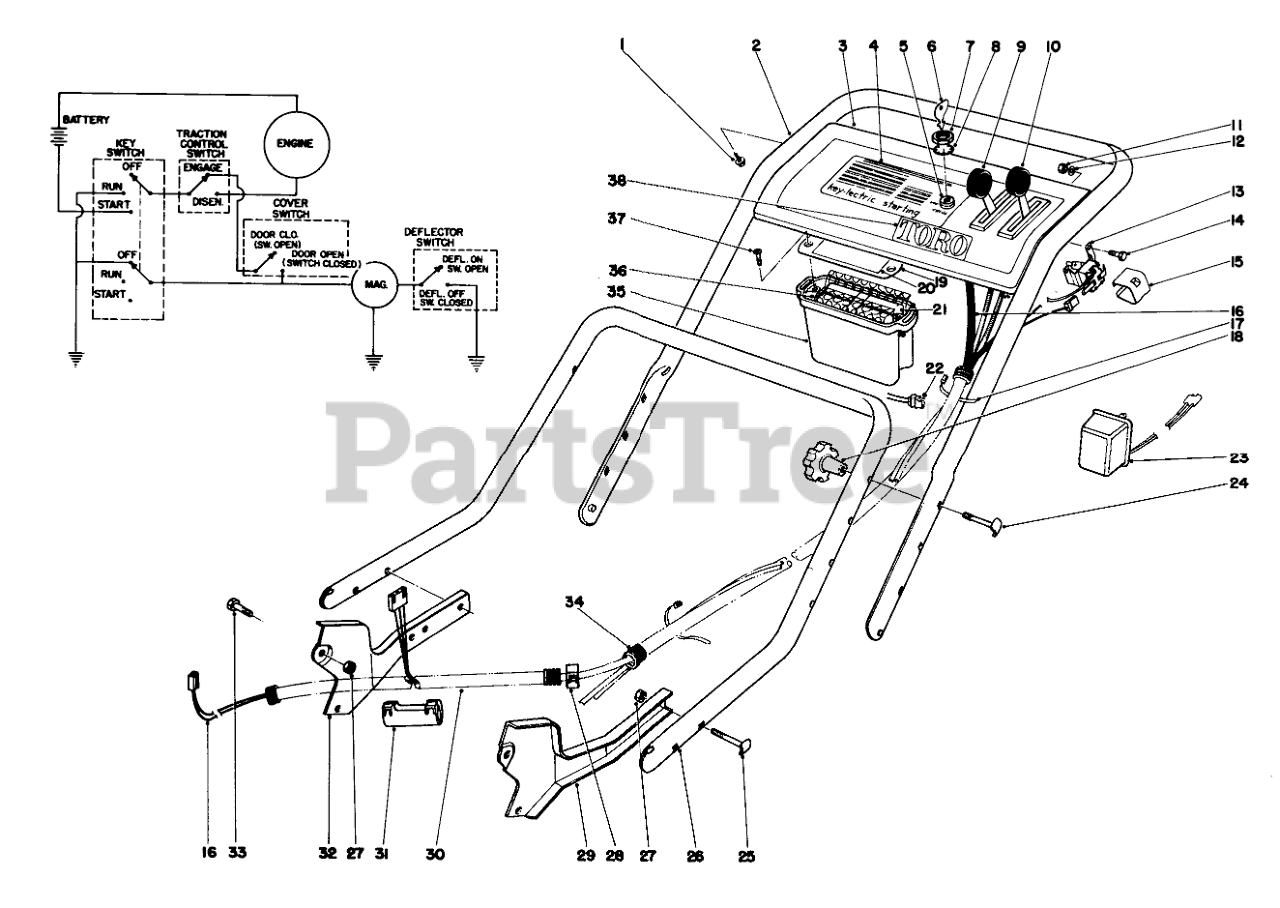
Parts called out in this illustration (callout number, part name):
1	SCREW-HWHTF
2	Upper Handle
3	Control Plate
4	Decal-Control Plate
5	SWITCH-STARTER
6	Key
7	NUT-HH
8	WASHER-TOOTH, INTERNAL
9	SPEED CONTROL
10	Traction Control
11	NUT-HEX
12	WASHER-FLAT
13	CONTROL SWITCH
14	SCREW-HH
15	Cover Switch
16	Wiring Harness
17	TIE-CABLE
19	Cover
20	Decal Battery
21	12 Cell Battery Pack
22	Plug & Wire
23	Charger
24	HANDLE SCREW
25	Handle Screw
26	Lower Handle
27	Nut
28	RING FITTING
29	Latch Handle L.H.
30	WIRING HARNESS COVER
31	Breakout Fitting
32	RH HANDLE LATCH
33	Screw
34	Upper Wiring Harness
35	Container Pack
36	Spacer
38	Decal
